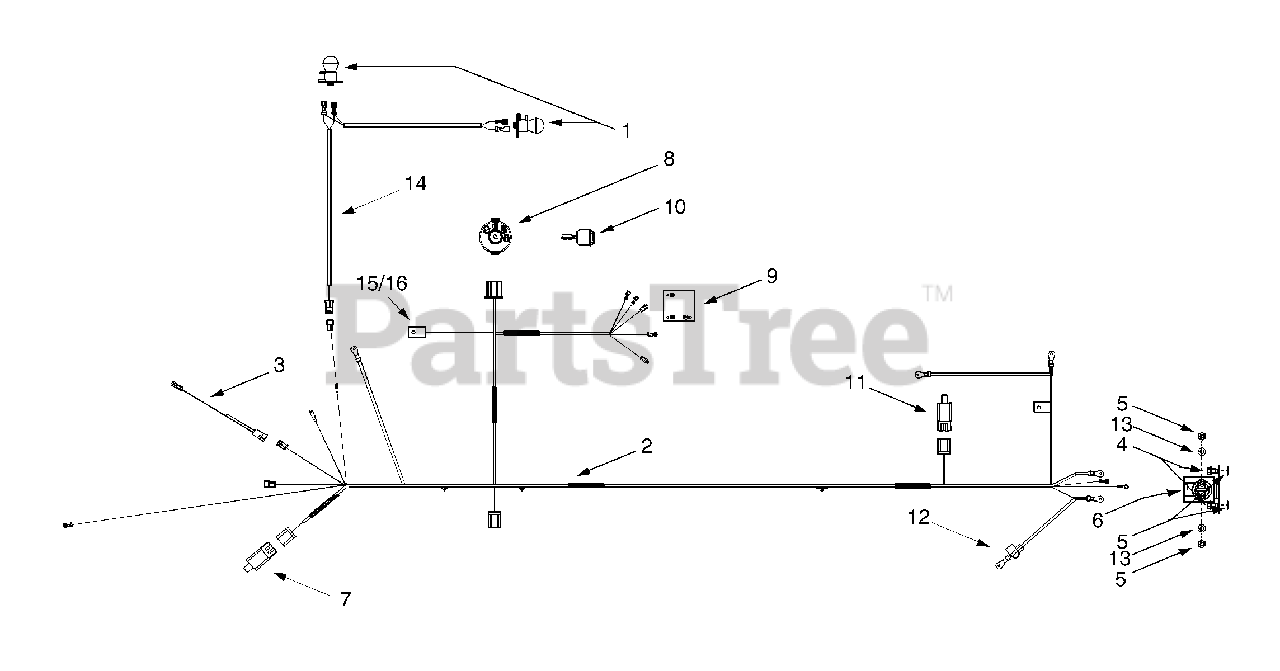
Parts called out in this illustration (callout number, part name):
1	Bulb/Socket Headlight Assembly
2	Wiring Harness w/o Ref. 14
3	Harness Adapter, #18 x 5
4	Self-tapping Screw, 1/4-20 x .5
5	Hex Nut, 1/4-20
6	Solenoid, 12-volt, 100 Amp
7	Snap Mount Safety Interlock Switch (Brake)
8	Ignition Switch
9	Systems Indicator Monitor
10	Ignition Key w/ Plastic Cover
10	Ignition Key w/o Plastic Cover
11	Safety Plunger Switch (Seat)
12	Positive Terminal Cover (Boot)
13	Lock Washer, 1/4
14	Headlight Harness
15	Fuse Holder
16	20-amp Fuse
